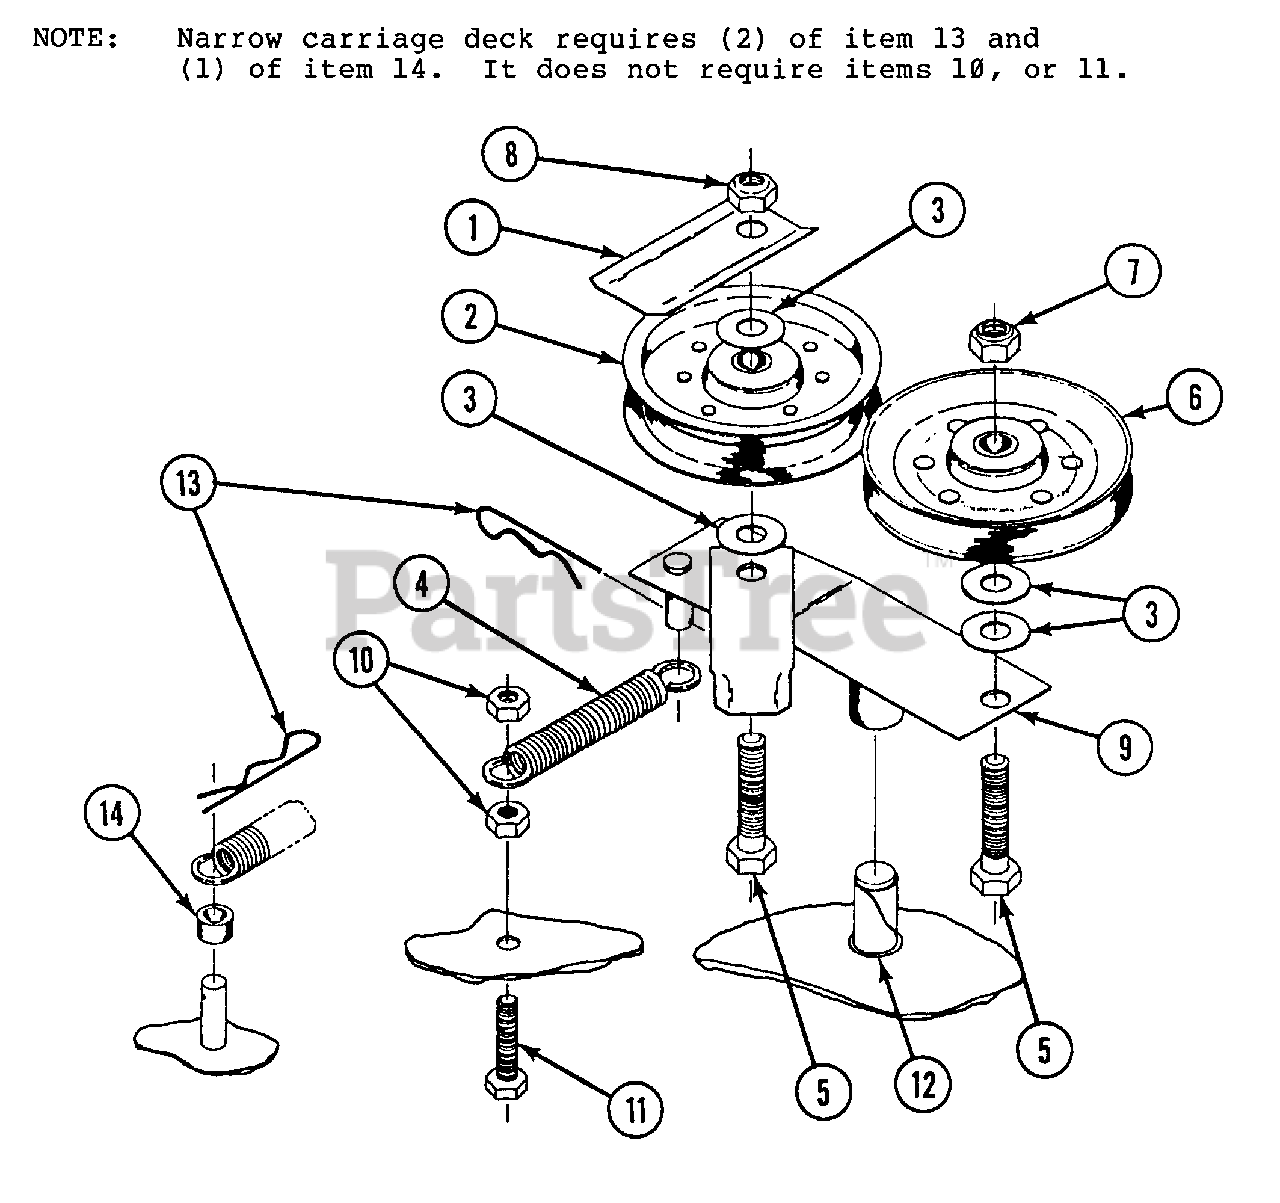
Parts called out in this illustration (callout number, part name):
1	PLATE, BELT STOP
2	PULLEY, FLAT IDLER 1/2 BORE, 4" O.D.
3	FLAT WASHER, 1/2
4	SPRING EXTENSION, 3/4 X 4" O.A.L
5	CAPSCREW, HX HD: 1/2-13 X 2 GR.5
6	PULLEY, V-IDLER, 1/2 BORE, 4-3/8 O.D.
7	NUT, 1/2-13, NYLOC
8	NUT, 1/2-13, STOVER
9	DOUBLE IDLER WELDMENT
10	NUT, 3/8-24, M-F LOCKNUT
11	CAPSCREW, HX HD: 3/8-24 X 1 1/4 GR.5
12	BUSHING, NYLON, 5/8 BORE
13	PIN, HAIR SPRING, 1/8 X 2-1/2
14	SPRING SPACER
